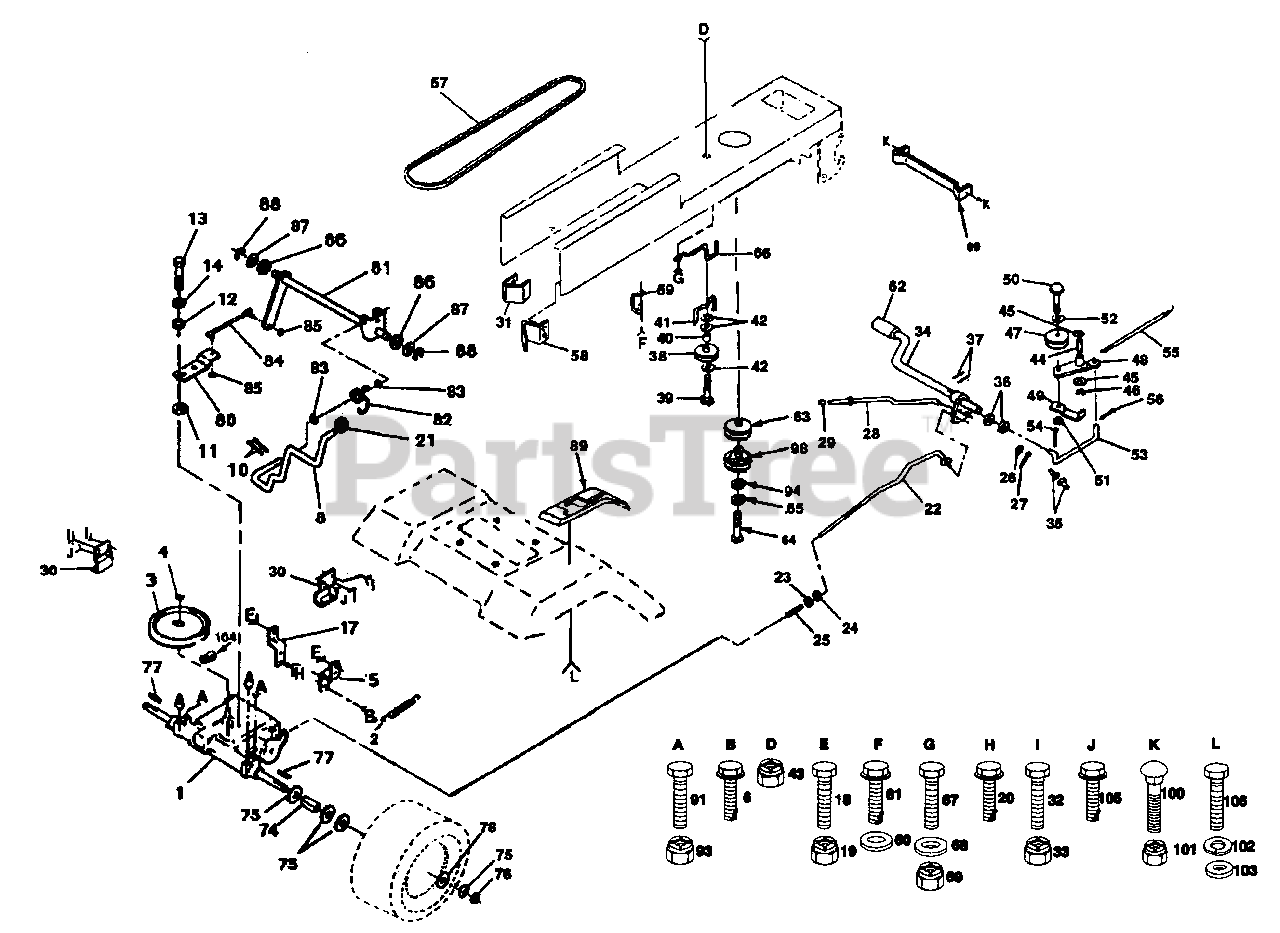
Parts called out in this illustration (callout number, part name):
1	Transaxle 6sp Hvy Dana (AYP part number)
2	Spring Return Brake T/a Zinc (AYP part number)
3	Pulley Transaxle Alum (AYP part number)
4	Ring Retainer # 5100-62 (AYP part number)
5	Strap Pnt Torque 30 Deg Blk (AYP part number)
6	Screw Thdrol 5/16-18 X 3/4 Tyt
8	Rod Shifter (AYP part number)
10	Pin Cotter 1/8 X 1 Cad (AYP part number)
11	Washer Plate Shf 388 Sq Hole (AYP part number)
12	Washer 15/32 X 3/4 X 16Ga (AYP part number)
13	Bolt Fin Hex 1/4-28unfx3/4 Gr8 (AYP part number)
14	Washer Lock Hvy Helical 1/4 (AYP part number)
17	Strap Pnt Torque 30 DEG BLK (AYP part number)
18	Bolt Fin Hex 3/8-16unc X 3/4 (AYP part number)
19	Nut Crownlock 3/8-16 Unc
20	Screw Thdrol 5/16-18 X 3/4 Tyt
21	Knob Duckhead 3/8 - 16 (AYP part number)
22	Rod Brake Lt (AYP part number)
23	Nut Lock Hex W/wsh 3/8-16unc (AYP part number)
24	Nut Hex Jam 3/8-16 Unc (AYP part number)
25	Spring Rod Brake 2 00 Zinc (AYP part number)
26	Washer 13/32 X 13/16 X 16 Ga (AYP part number)
27	Pin Cotter 1/8 X 3/4 Cad (AYP part number)
28	Rod Brake Parking (AYP part number)
29	Cap Parking Brake Black (AYP part number)
30	Bracket Transmission (AYP part number)
31	Keeper Belt Lh Lt 14 Ga (AYP part number)
32	Bolt Fin Hex 5/16 - 18 (AYP part number)
33	Nut Crownlock 5/16 - 18
34	Shaft Asm Pedal Foot 1 930 (AYP part number)
35	Bearing Nylon Blk 629 ld (AYP part number)
36	Washer 21/32 X 1 X 16 Ga (AYP part number)
37	Pin Roll 3/16 X 1 (AYP part number)
38	Pulley Idler Flat (AYP part number)
39	Bolt Fin Hex 3/8-16unc X 2-3/4 (AYP part number)
40	Spacer Split 395 X 59 Bzp (AYP part number)
41	Keeper Belt Retainer (AYP part number)
42	Washer 13/32 X 13/16 X 12 Ga (AYP part number)
43	Nut Crownlock 3/8-16 Unc
44	Bearing Nyl 503 X 628 X 1 25 (AYP part number)
45	Washer Hardened (AYP part number)
46	Ring Klip #t5304-50 (AYP part number)
47	Pulley Idler V Groove Plastic
48	Bellcrank Asm (AYP part number)
49	Retainer Belt Style Spring (AYP part number)
50	Bolt Hex Hd 3/8-16unc X 1-1/2 (AYP part number)
51	Nut Crownlock 3/8-16 Unc
52	Washer 13/32 X 13/16 X 16 Ga (AYP part number)
53	Link Clutch 7 66 (AYP part number)
54	Pin Cotter 1/8 X 3/4 Cad (AYP part number)
55	Spring Return Clutch 6 75 (AYP part number)
56	Pin Cotter 1/8 X 3/4 Cad (AYP part number)
57	V-belt Ground Drive 95 25 (AYP part number)
58	Keeper Belt Rh Lt Pnt/zinc 16g (AYP part number)
59	Retainer Belt Chassis Lh Zinc (AYP part number)
60	Washer 13/32 X 13/16 X 12 Ga (AYP part number)
61	Screw Thdrol 3/8-16x3/4 Ty-tt (AYP part number)
62	Cover Pedal Blk Std (AYP part number)
63	Pulley Engine (AYP part number)
64	Bolt, Hex M10-1.5 x 110 (AYP part number)
65	Washer Lock Hvy Hlcl Spr 7/16 (AYP part number)
66	Keeper Belt Engine Lh Lt (AYP part number)
67	Bolt Fin Hex 3/8-16unc X 1 (AYP part number)
68	Washer 13/32 X 13/16 X 12 Ga (AYP part number)
69	Nut Crownlock 3/8-16 Unc
74	Spacer Split 80x 94 Cad/zinc (AYP part number)
75	Washer 25/32 X 1 1/4 X 16 Ga (AYP part number)
76	Ring E (AYP part number)
77	Key Square 2 0 X 1845/ 1865 (AYP part number)
78	Washer 25/32 X 1 5/8 X 16ga (AYP part number)
80	Arm Pnt Shift T/a (AYP part number)
81	Shaft Asm Pnt Shifter (AYP part number)
82	Spring Torsion T/a (AYP part number)
83	Washer 17/32 X 3/4 X 16ga (AYP part number)
84	Rod Link Shift Adj 3 710 (AYP part number)
85	Nut Nylock 1/4-28 (AYP part number)
86	Bushing Pivot W/ 180 Step Pm (AYP part number)
87	Washer Shim 53 X 1 25 X 0598 (AYP part number)
89	Console Shift 5sp W/ign Lt Srs
91	Bolt Fin Hex 5/16-18uncx 2-1/2 (AYP part number)
93	Nut Crown Lock 5/16-18
94	Washer 1 - 1/2 OD x 15/32 ID x .250 (AYP part number)
98	Clutch Elc 70 Ft/Lbs 1" Vert Sha (AYP part number)
99	Retainer Asm. (AYP part number)
100	Bolt, Carriage 5/16 - 18 x 3/4
101	Nut, Crownlock 5/16 - 18 unc
102	Washer, Lock #8 (AYP part number)
103	Washer 3/16 x 7/16 x 18 Ga. (AYP part number)
104	Clip Fuel Line (AYP part number)
105	Screw Thdrol 3/8 - 16 x 3/4 (AYP part number)
106	Screw #8 x 1/2 (AYP part number)
